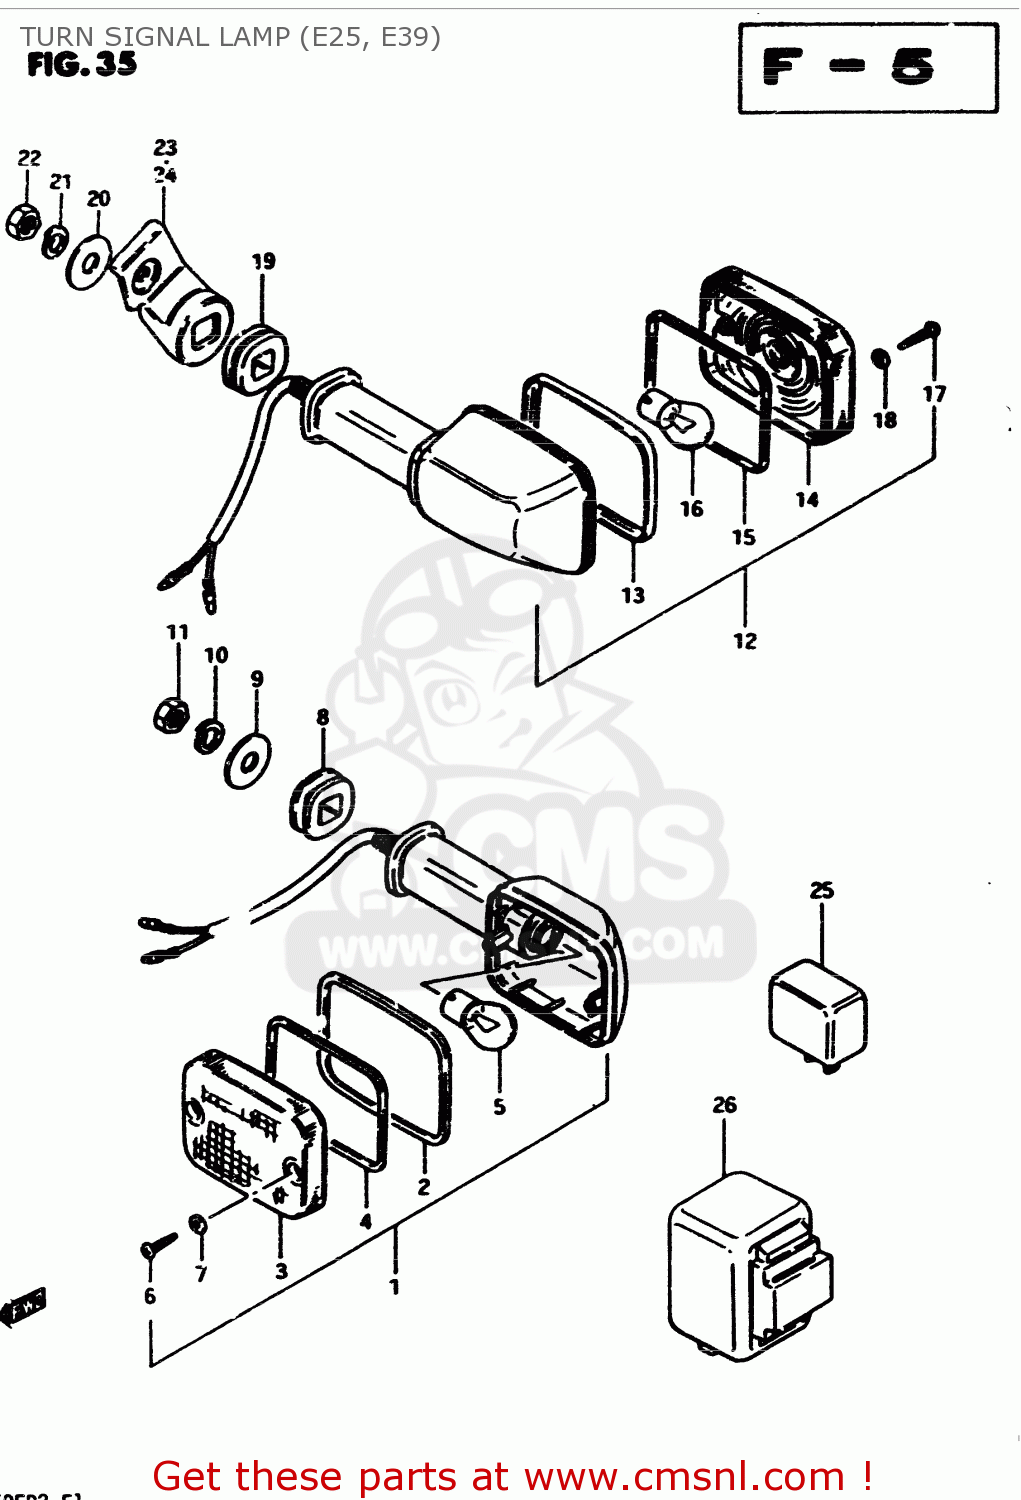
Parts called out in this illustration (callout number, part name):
1	LAMP ASSY,FR T
2	RIM
3	LENS
4	GASKET (NAS)
5	BULB(12V21W)
6	SCREW
7	GASKET (NAS)
8	CUSHION
9	WASHER (10.5X30X2.3)
10	LOCK WASHER
11	NUT
12	LAMP ASSY,RR T
13	RIM
14	LENS
15	GASKET (NAS)
16	BULB(12V21W)
17	SCREW
18	GASKET (NAS)
19	CUSHION
20	WASHER (10.5X30X2.3)
21	LOCK WASHER
22	NUT
23	BRACKET,REAR TURN SIGNAL
24	BRACKET,REAR TURN SIGNAL
25	RELAY,TURN SIGNAL
26	RELAY, TURN SIGNAL
